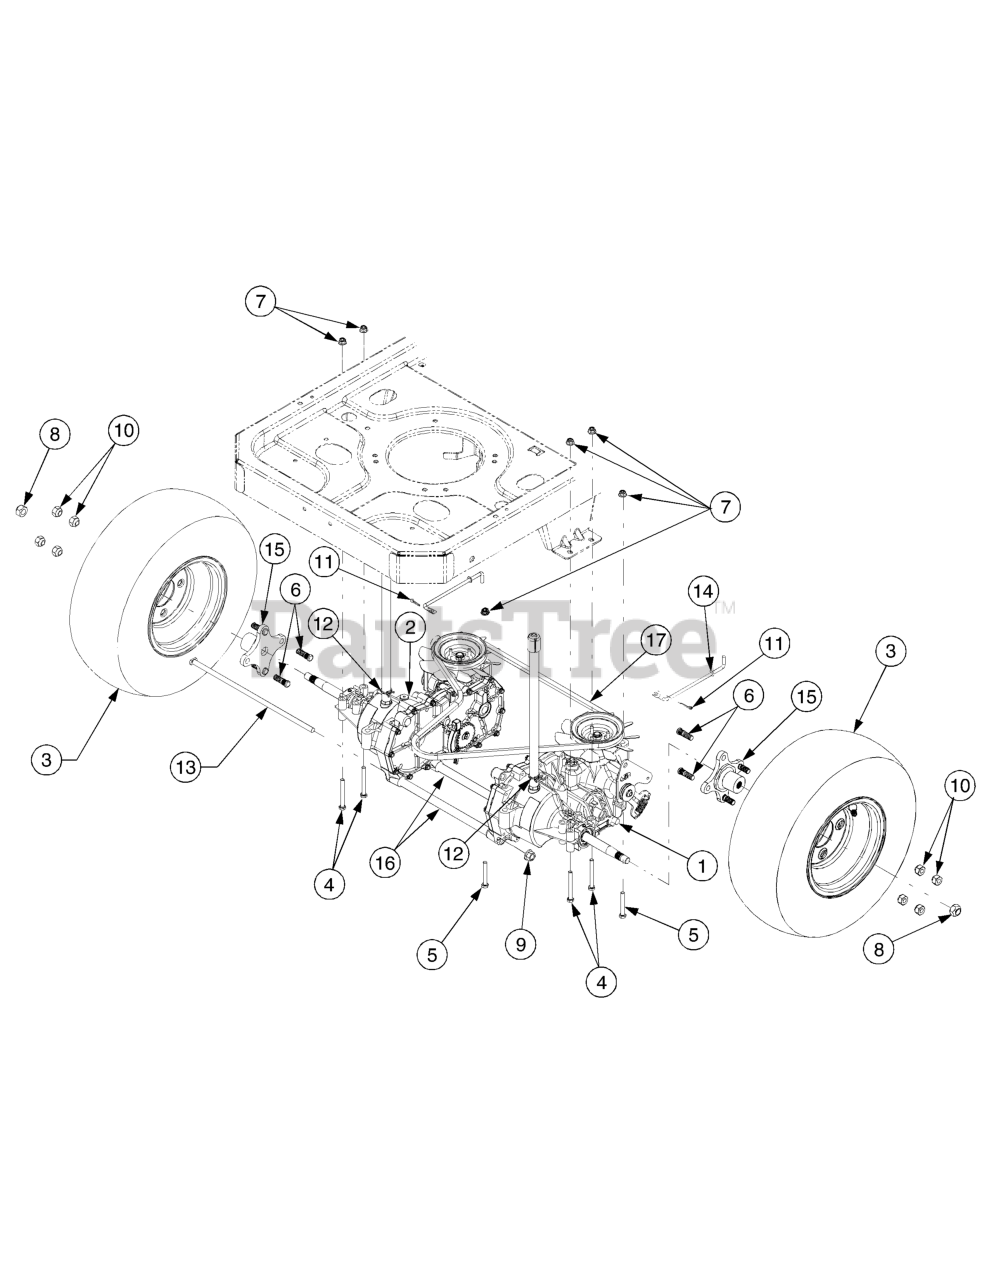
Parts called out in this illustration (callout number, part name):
1	Transmission Assembly, RH, Service Kit
2	Transmission Assembly, LH, Service Kit
3	Wheel Assembly, 18 x 9.5 x 8, RZT50
4	Screw, Hex Cap, 5/16-18 x 2.75 GR5
5	Screw, Hex Cap, 5/16-18 x 2.25 GR5
6	Stud, Rib Neck, 7/16-14 x 1.6
7	Nut, Hx Insert Flange Lck, 5/16-18
8	Nut, Hex Lock, 9/16-18 GRC
9	Nut, Hex Flange Lock, 7/16-20 GrB
10	Nut, Lug, 7/16-14
11	Pin, Cotter, 3/32 x .75
12	Clamp, Hose
13	Rod, .405 x 14.0
16	Tube, .45 x .69 x 10.2
17	V-Belt, Type A Sec x 57.7
